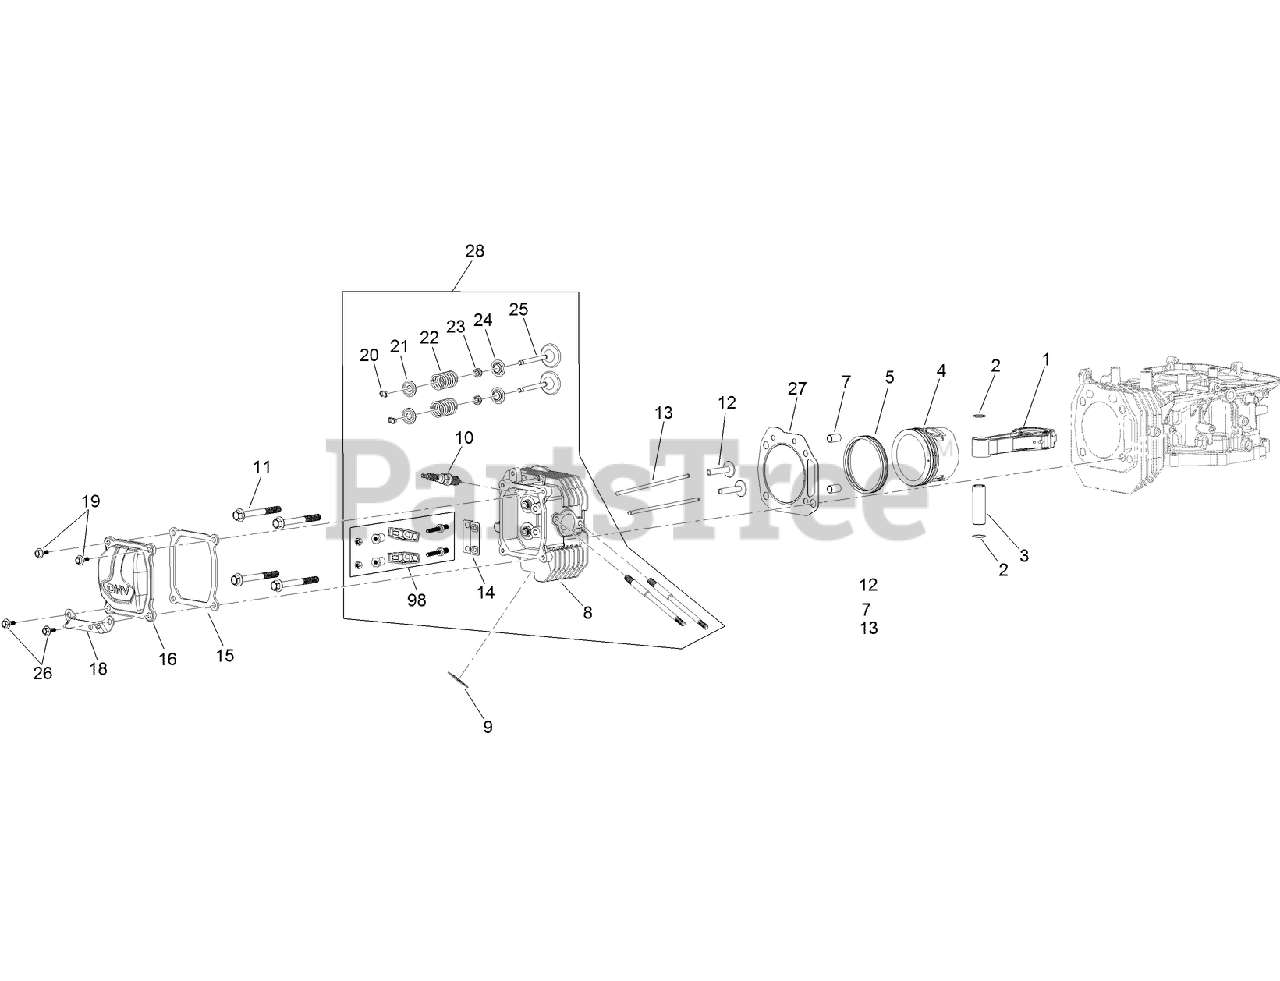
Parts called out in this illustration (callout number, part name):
1	CONNECTING ROD ASM
2	RING-RETAINING, PISTON PIN
3	PIN-PISTON
4	PISTON
5	RING SET
7	PIN-DOWEL
8	HEAD-CYLINDER
9	GASKET-EXHAUST
10	PLUG-SPARK
11	SCREW-HHF
12	LIFTER-VALVE
13	ROD-PUSH
14	PLATE-GUIDE, PUSH ROD
15	GASKET-COVER, VALVE
16	COVER-VALVE
18	BRACKET-MUFFLER
19	SCREW-SHOULDER, HHF
20	KEEPER-VALVE
21	RETAINER-SPRING, VALVE
22	SPRING-VALVE
23	SEAL-STEM, VALVE
24	SEAT-SPRING, VALVE
25	VALVE SET
26	SCREW-SHOULDER, HHF
27	GASKET-CYCLINDER
28	COMPLETE HEAD ASM
98	ROCKER ARM KIT
